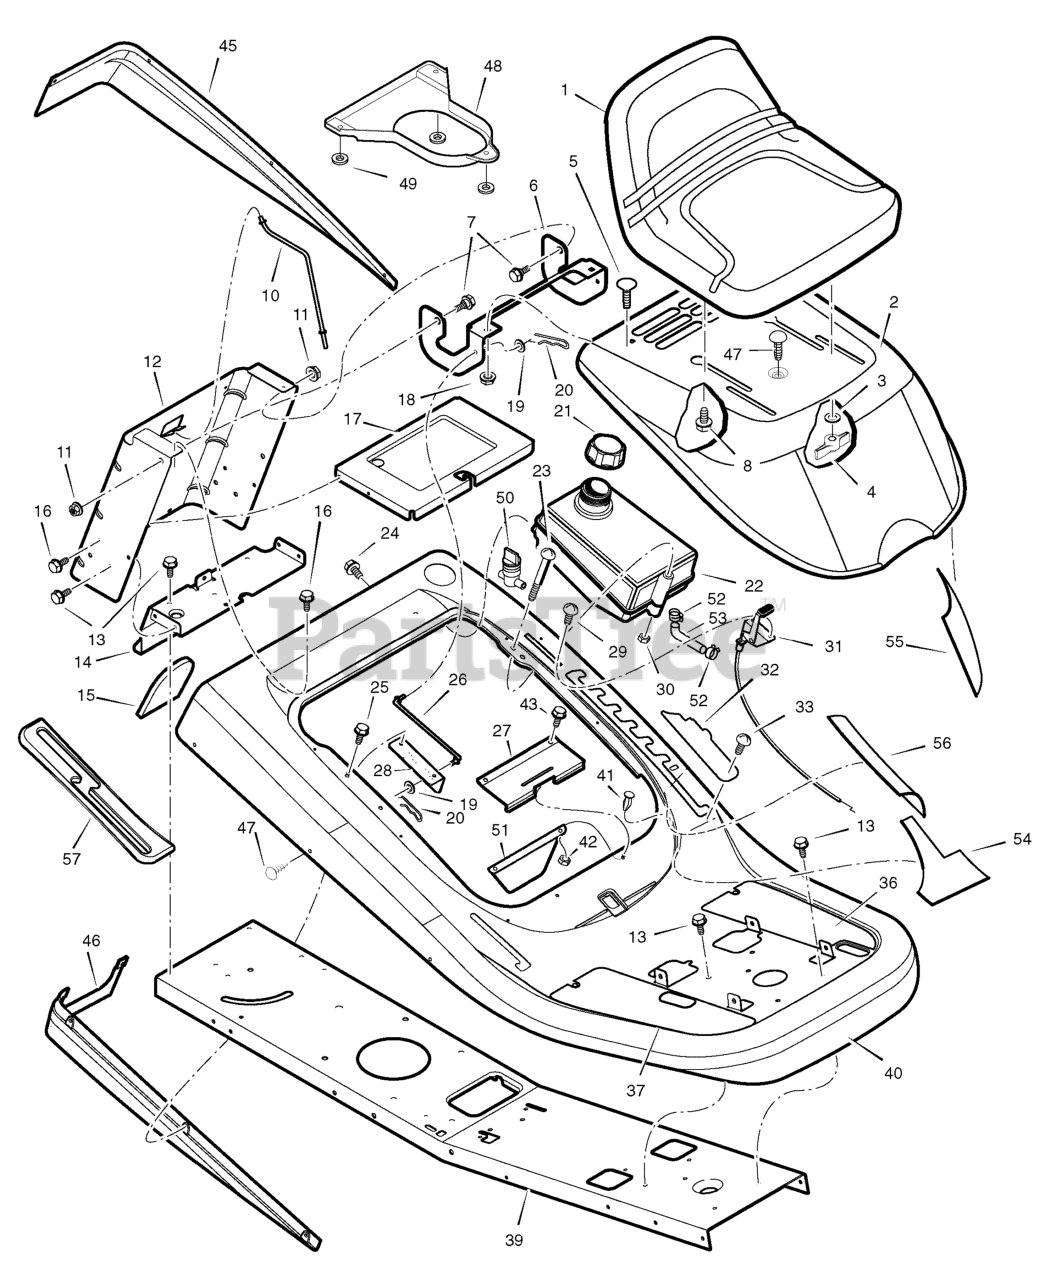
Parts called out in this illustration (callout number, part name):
4	BOLT, Wing
5	BOLT, Carriage
6	BRACKET, Hinge
7	BOLT, Shoulder
8	BOLT, Shoulder
10	ROD, Battery
11	NUT, Flange
12	PLATE, Rear
14	PLATE, Hitch
17	TRAY, Battery
18	NUT, Flange
20	PIN, Cotter
21	CAP, Fuel Tank
22	TANK, Fuel
23	SCREW
26	ROD, Hood Prop
27	SPRING, Seat Deck
28	BRACKET, Prop Rod
30	NUT, NY-Lock
31	CONTROL, Throttle
32	COVER, Detent (Black)
33	BOLT, Shoulder
36	FOOTMAT, Left (Black)
37	FOOTMAT, Right (Black)
39	FRAME
40	DECK, Seat
42	NUT
44	KIT, Foil Heat Shield
45	TRIM, Left
46	TRIM, Right
47	FASTENER, Panel
49	NUT, Hex 5/16-18
50	VALVE, Fuel Shutoff
51	SHIELD, Heat
52	HOSE, Clamp
53	FUEL, Hose
54	HEAT SHIELD, Hood
55	REFLECTOR TAPE, Heat Shield Hood
56	REFLECTOR TAPE, Heat Shield Upper
57	Cover, Long Black
